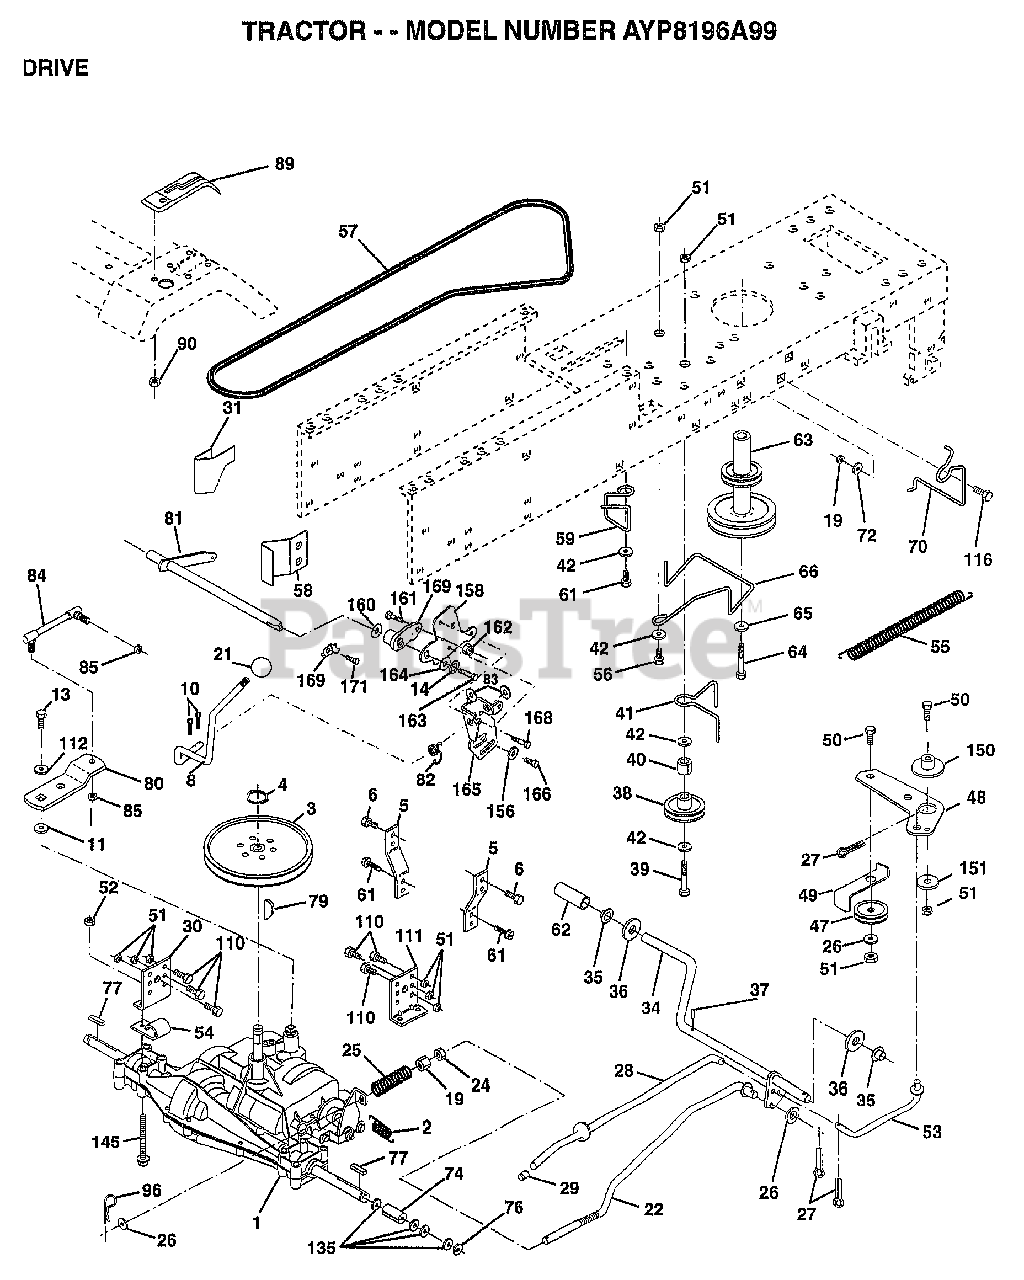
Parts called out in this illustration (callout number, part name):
3	PULLEY TRANSAXLE
4	RING
5	STRAP TORQUE
6	SCREW
8	ROD.SHIFT.FEND.ADJ.YT
10	PIN COTTER 1/8
11	WASH-SHFT PLT LT
13	BOLT.1/4-28.W/PAT
14	LOCKWASHER
19	NUT
21	KNOB T (1/2-HOLE)
22	ROD.ASM.BK.44.MWR
24	NUT
25	"SPRING,ROD BRAKE"
26	WASHER
27	COTTER PIN
28	ROD.BRAKE.PARK.LT
30	BRKT TRANS LH
31	KEEPER BELT LH
34	SHAFT ASM-PEDAL F
35	NYLON BEARING
36	WASHER LT
38	FLAT IDLER PULLEY
39	BOLT
40	SPACER T
41	"KEEPER,BELT.IDLER FLAT"
42	WASHER
48	BELLCRANK.CLUTCH
49	RETAIN BELT
53	"LINK, CLUTCH T"
54	"CLIP,INSULATOR"
55	"SPRING, RETURN LT"
57	V-BELT.DRIVE
58	"KEEPER,BELT RH"
59	KEEPER BELT CNTSP
61	SCREW
62	PEDAL COVER T
63	PULLEY.ENGINE
64	BOLT
65	LOCKWASHER
66	KEEPER-BELT
70	"GUIDE.BELT,RH ENG"
72	WASHER
74	SPACER HYT
76	E RING HYT
77	SQ KEY STD
80	"ARM,SHIFT"
81	SHAFT ASM. CROSS TAPERED
82	"SPRING,TORSION"
83	WASHER
84	LINK TRANSAXLE
85	NUT.CNT.LOCK.1/4
89	CONSOLE.SHIFT.6SP.GTV.BLACK
90	NUT
96	RETAINER M
111	BRKT TRANS RH
112	WASHER PM
116	BOLT RDHD 3/8-16
135	WASHER
145	BOLT.HEX.FLGHD
150	BUSHING.BELLCRANK.GRD.DR
151	WASHER
156	WASHER.SRRTD.5/16
158	BRKT.SHIFT.MOUNT
159	HUB.SHIFT
160	WASHER
161	BOLT T
164	WASHER.5/8X.281X10GA
165	BRKT.PIVOT.LEVER
166	SCREW.5/16-18X5/8
168	BOLT.SHOULDER.5/16-18X.561
169	PLATE.FASTENING
171	SCREW LT
